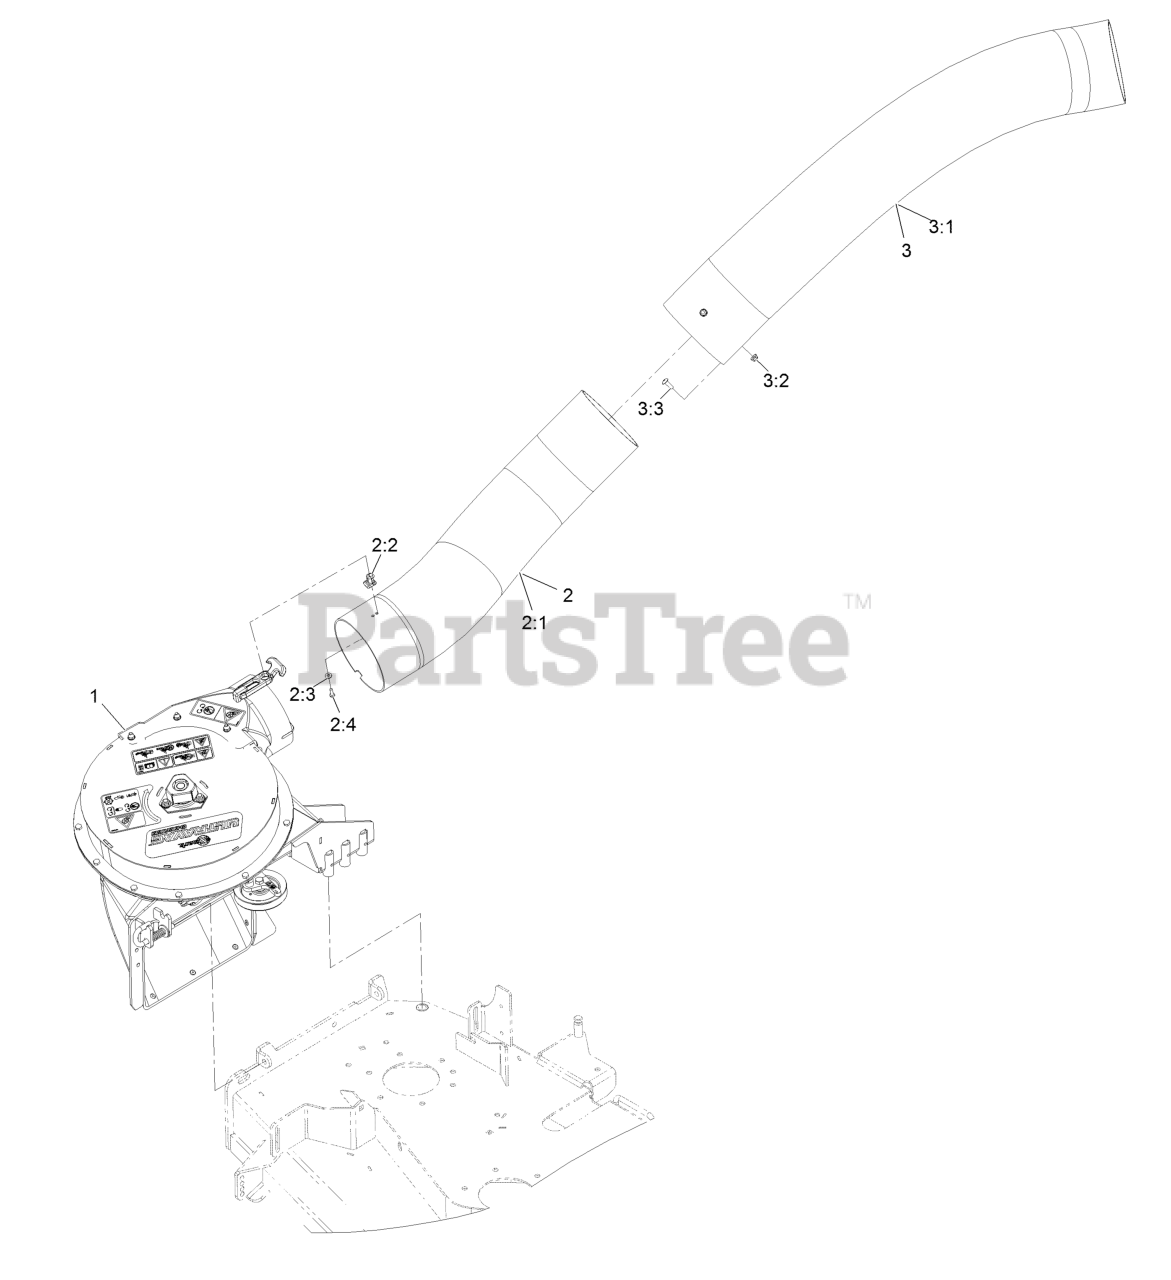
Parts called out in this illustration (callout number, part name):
1	ASM-BLOWER UV
2	LOWER TUBE ASM
2:1	TUBE-LOWER
2:2	LATCH-KEEPER
2:3	WASHER-FLAT
2:4	SCREW-PPH
3	UPPER TUBE ASM
3:1	TUBE-UPPER
